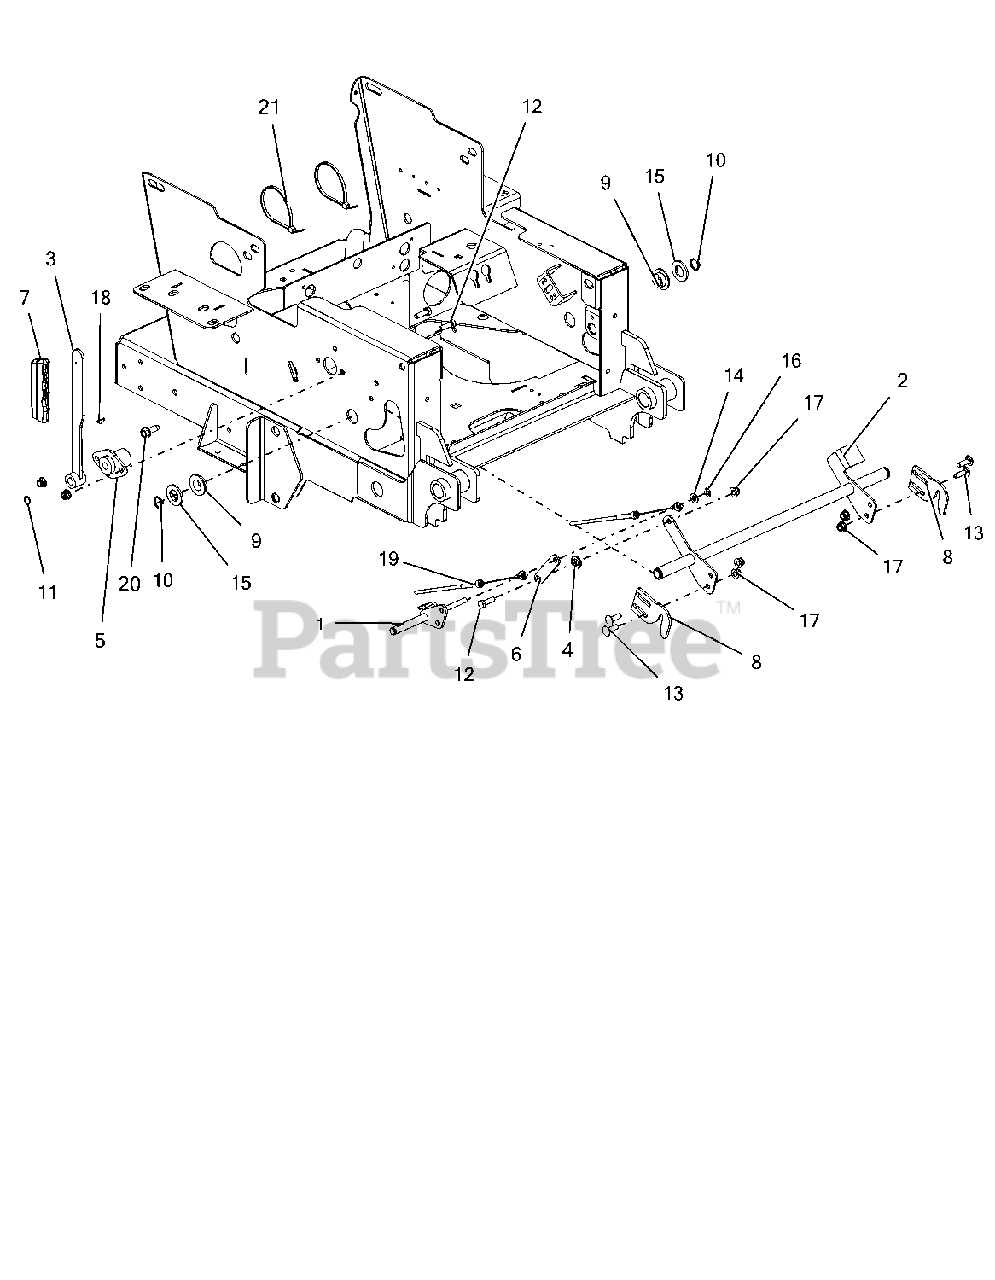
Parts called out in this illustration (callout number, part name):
1	WLDMT, PARK BRAKE ARM
2	WLDMT, NEUTRAL INTERLOCK
3	WLDMT, PARKING BRAKE ARM
4	BSHG, FLG .325X.499X.26X.88
5	BSHG, FLANGE .500 ID
6	PLATE, NEUTRAL INTERLOCK
7	GRIP, PARKING BRAKE (YELLOW)
8	NEUTRAL, LOCK LATCH-BLACK
9	BSHG, FLANGE .762 X 1.48 X .44 NYLON
10	RG-RTNG-EXT .750x.078
11	RG-RTNG-EXT .500x.050
12	BLT-HEX .31-18X1.00 GR5 YWZC
13	BLT-RDHDSQSHNK .31-18X1.00 G5 Y
14	WSHR-FL-STL.344X.688X.065YWZC
15	WSHR-FL-STL.812X1.50X.135YWZC
16	NUT, PUSH .312
17	NUT-LK-NYL-FLG .31-18 YWZC
18	KEY, WDRF .13x.63 HRD#5 GM124545 P
19	CABLE, BRAKE ACTUATING
20	SCR-TAP .38-16X1.00 HWH TR YZ
21	CABLE, TIE 5.50 LG
